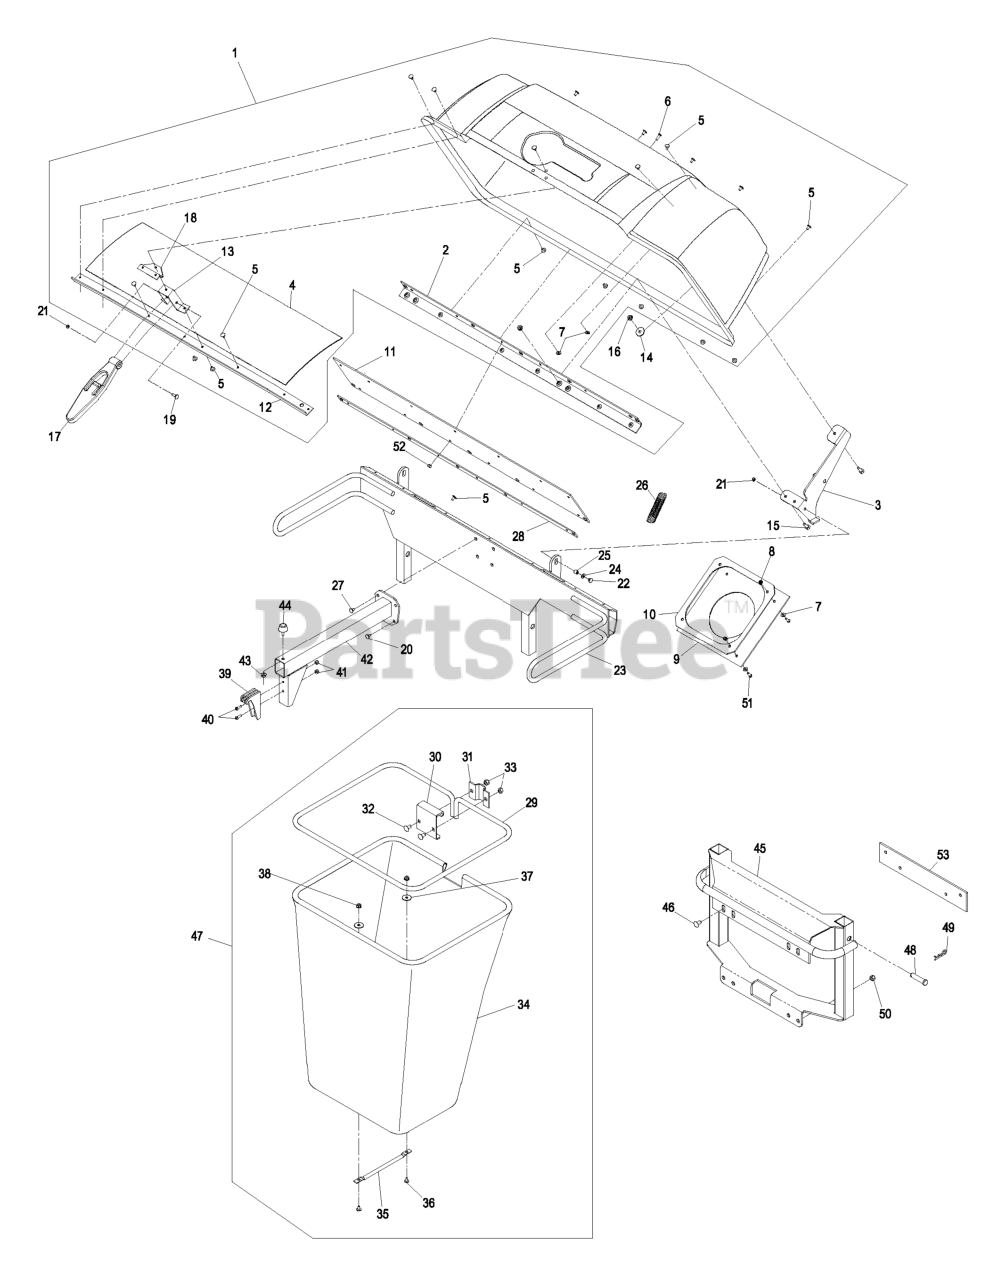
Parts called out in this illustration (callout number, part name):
1	ASM, HOOD
2	STIFFENER-BAGGER, TOP
3	HINGE ASM
4	SCREEN-BAGGER
5	RIVET-BLIND
6	SCREW-HEAD, TRUSS
7	WASHER-FLAT
8	NUT-LOCK, NI
9	SEAL-CHUTE
10	CLAMP-SEAL
12	SUPPORT-SCREEN
13	ANCHOR-LATCH
15	SCREW-HH
18	REINFORCEMENT-LATCH
19	SCREW-HH
20	SCREW-HH
21	NUT-LOCK, NI
22	SCREW-HH
23	BAGGER UPRIGHT ASM
24	WASHER-FLAT
26	SPRING-EXTENSION
27	SCREW-HSBH
28	PLATE-BACKING
29	FRAME-BAG
30	HANGER-BAG
32	BOLT-CARR
33	NUT-LOCK, NI
35	HANDLE-BAG
36	BOLT-CARR
38	NUT-LOCK, NI
40	SCREW-PPH
42	SUPPORT-BAG
45	BAGGER MOUNT ASM
46	SCREW-HH
48	PIN-CLEVIS
49	PIN-COTTER
51	SCREW-PPH
52	NUT-LOCK, SIDE
53	SPACER,COUNTERWEIGH
